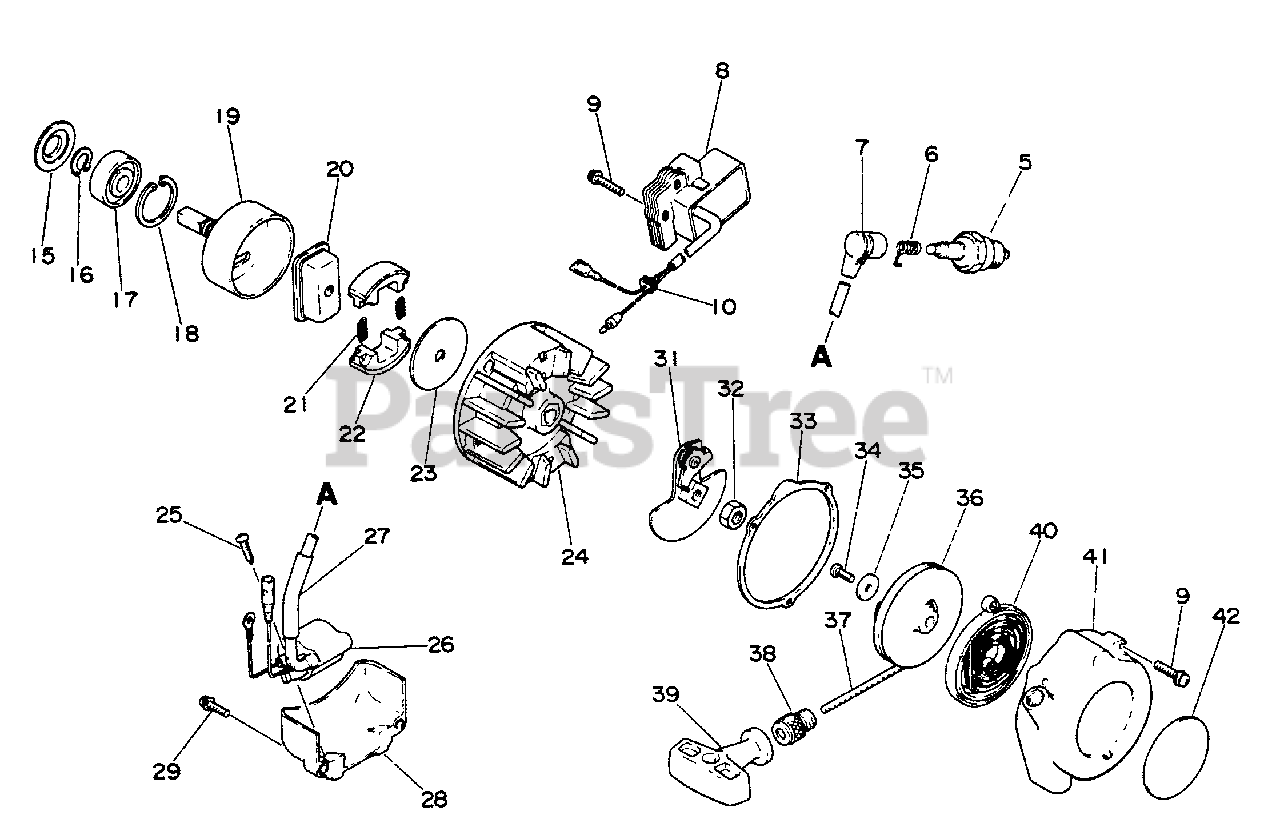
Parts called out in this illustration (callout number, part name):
5	SPARK PLUG - CJ8
6	TERMINAL, SPARK PLUG
7	CAP, SPARK PLUG
8	COIL, IGNITION
9	SCREW 4×20
15	STOPPER, PIPE
16	RING, RETAINING - 12
17	BEARING, BALL
18	RING, SNAP Ø32
19	DRUM, CLUTCH
20	BOSS, CLUTCH
21	SPRING, CLUTCH
22	SHOE, CLUTCH
23	PLATE, CLUTCH
24	FLYWHEEL
25	SCREW - 4×16 -- TAPPING
26	COIL, IGNITION
27	PIPE
28	COVER
29	SCREW 4×14
31	PAWL ASSY, STARTER
32	NUT 8×1.25
33	GASKET, STARTER
34	SCREW - 4×10
35	WASHER
36	REEL, ROPE
37	ROPE, STARTER 3.0×850
38	GUIDE, ROPE
39	GRIP, STARTER
40	SPRING, RECOIL
41	CASE, STARTER
42	LABEL, ECHO
